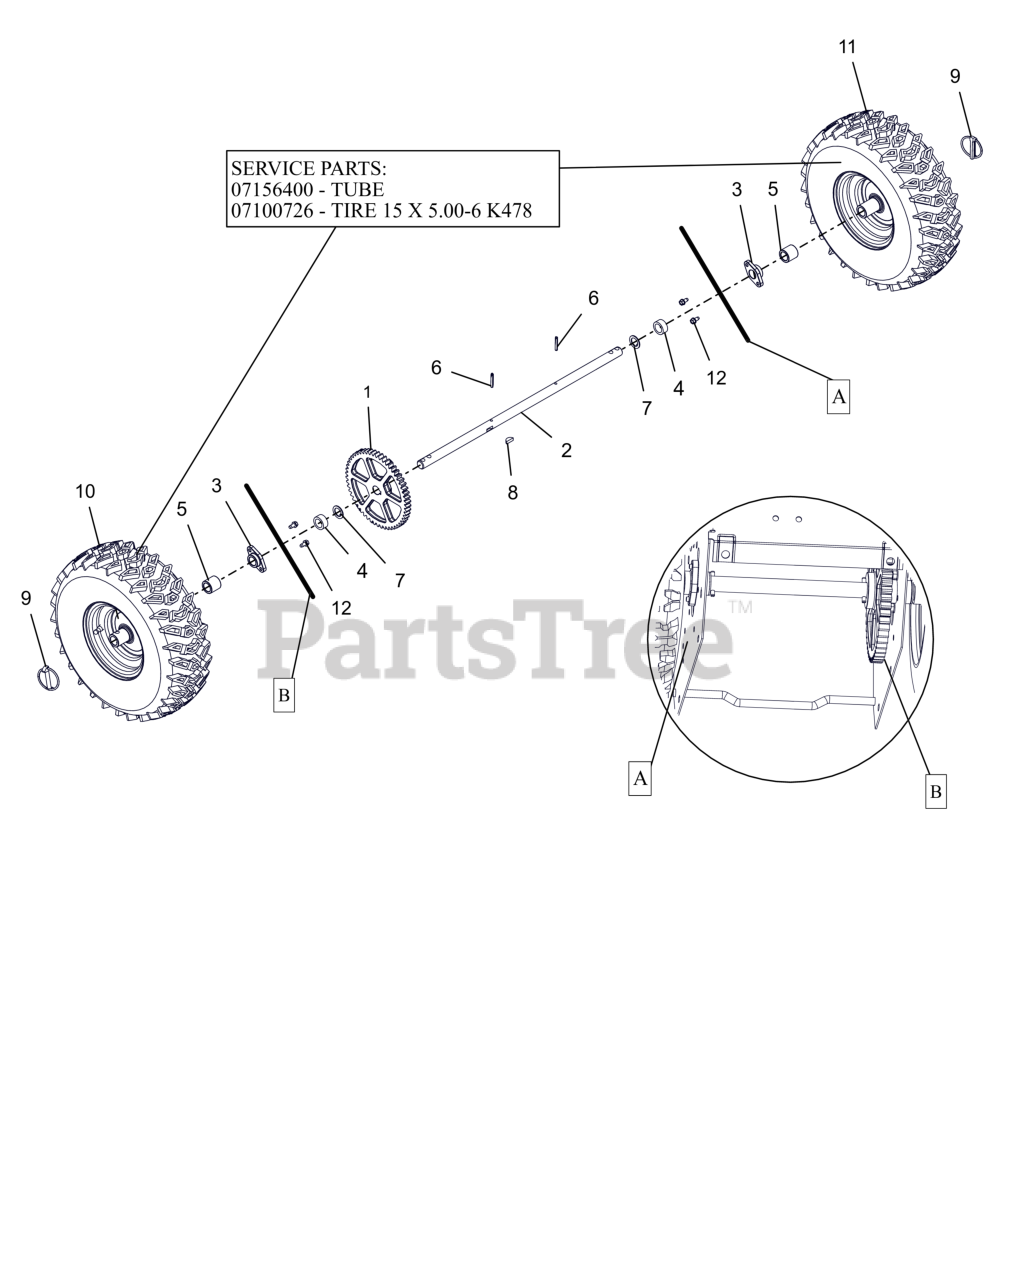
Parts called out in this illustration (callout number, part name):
1	SPUR GEAR, 54T .75ID X 6.75PD
2	AXLE, COMPACT 920,XXX 15" TIRE
3	BSHG .75X1.125X.65
4	BSHG-SLV .766 X 1.125 X .500
5	BSHG-SLV .75X1.12X1.062 NYL BK
6	PIN-ROLL .188X1.25
7	WSHR, FLT .754X1.125X.062 ZCC
8	KEY-WDRF .25X.750X.313 SAE91
9	PIN-LOK .31X1.75
10	TIRE/WHEEL,RH 15X5.00-6 PIN T2
11	TIRE/WHEEL,LH 15X5.00-6 PIN T2
11	TUBE 15 X 5.00-6
11	TIRE, 15X5.00-6 K478
12	SCR-TAP .25-20X.50 HWH ZCC
